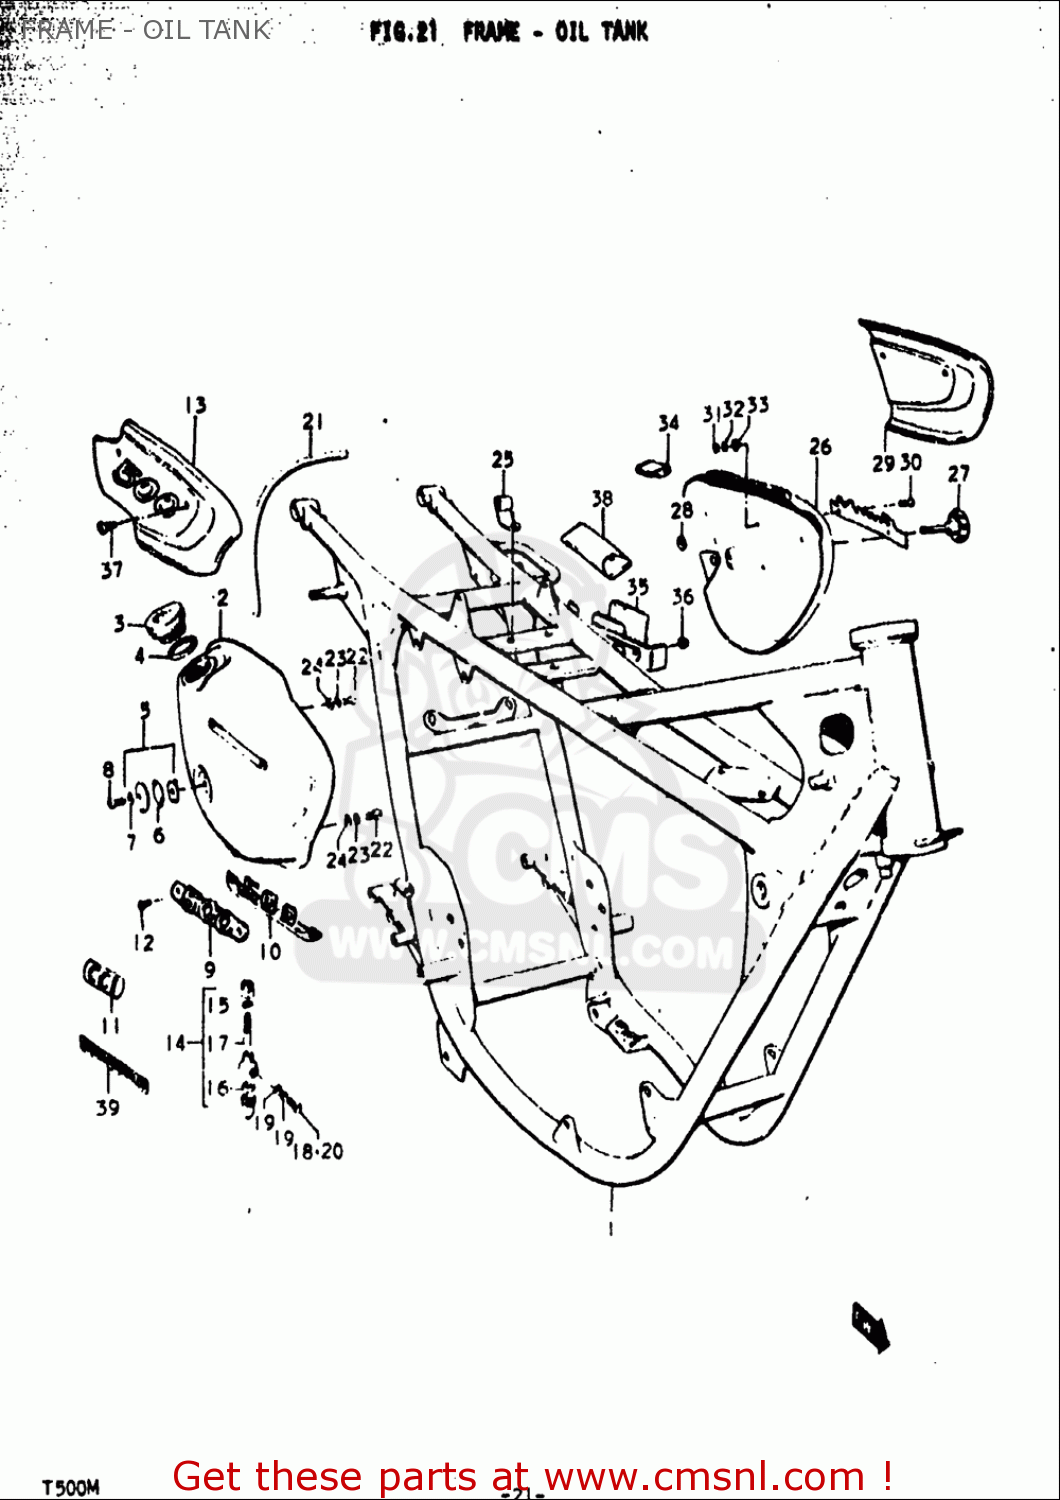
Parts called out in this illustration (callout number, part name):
3	CAP,OIL TANK
4	GASKET,OIL TANK FILLER CAP (NAS)
5	LENS SET,OIL INSPECTION
6	O RING(D:3,ID:23)
7	GASKET(5X9.5X1) (NAS)
8	SCREW
11	EMBLEM,CCIS
12	SCREW
15	GASKET,OIL OUTLET JOINT (NAS)
16	GASKET,STRAINER CUP (NAS)
17	UNIT,OIL FILTER
18	UNION BOLT
19	GASKET(6.2X11X1).2 (NAS)
20	OIL OUTLET JOINT NUT
21	HOSE(5X8X2000)
22	BOLT
23	WASHER,LOCK
24	WASHER
28	NUT
30	SCREW
31	NUT
32	WASHER,LOCK
33	WASHER
36	NUT
37	SCREW
